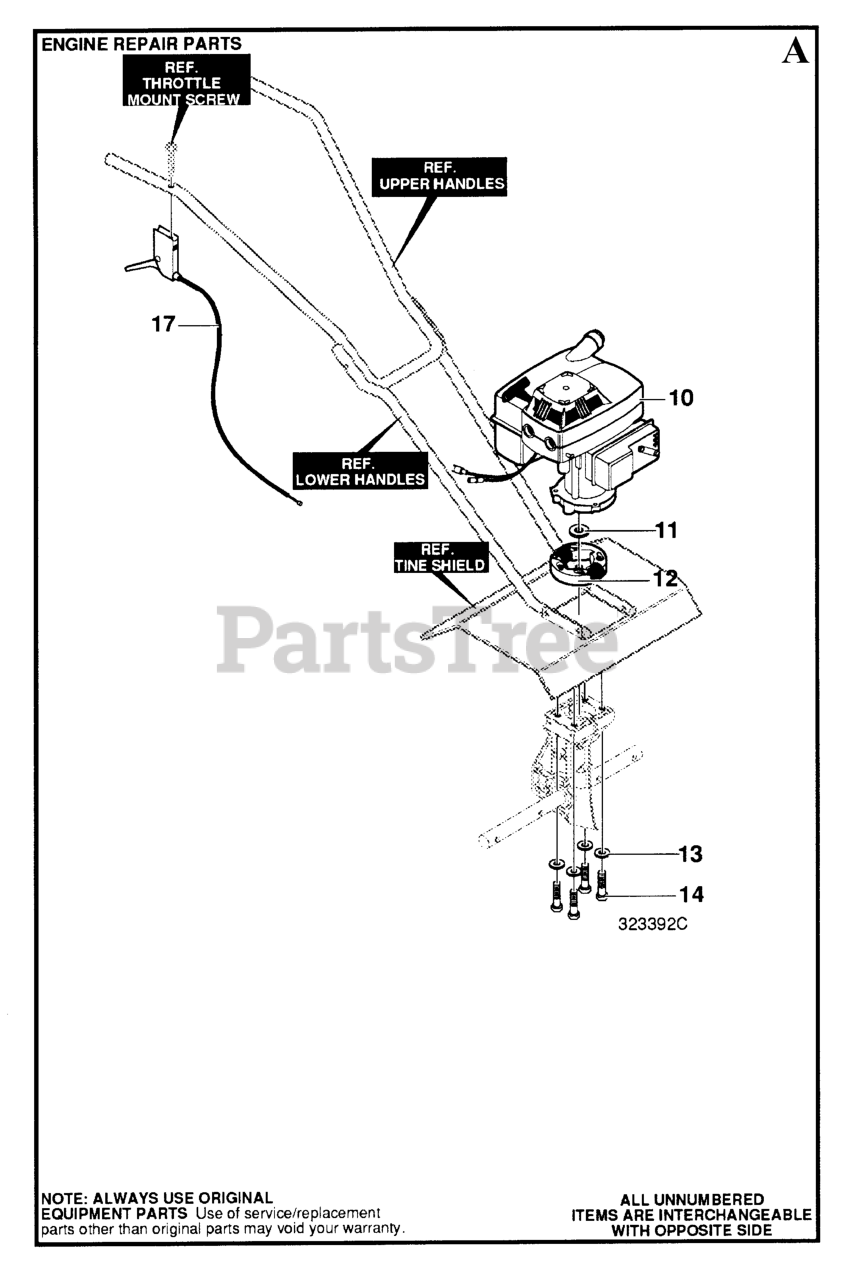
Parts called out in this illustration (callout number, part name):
10	See Engine Manual
13	LOCKWASHER
14	BOLT HEX FIN 1/4-20X1 3/4
